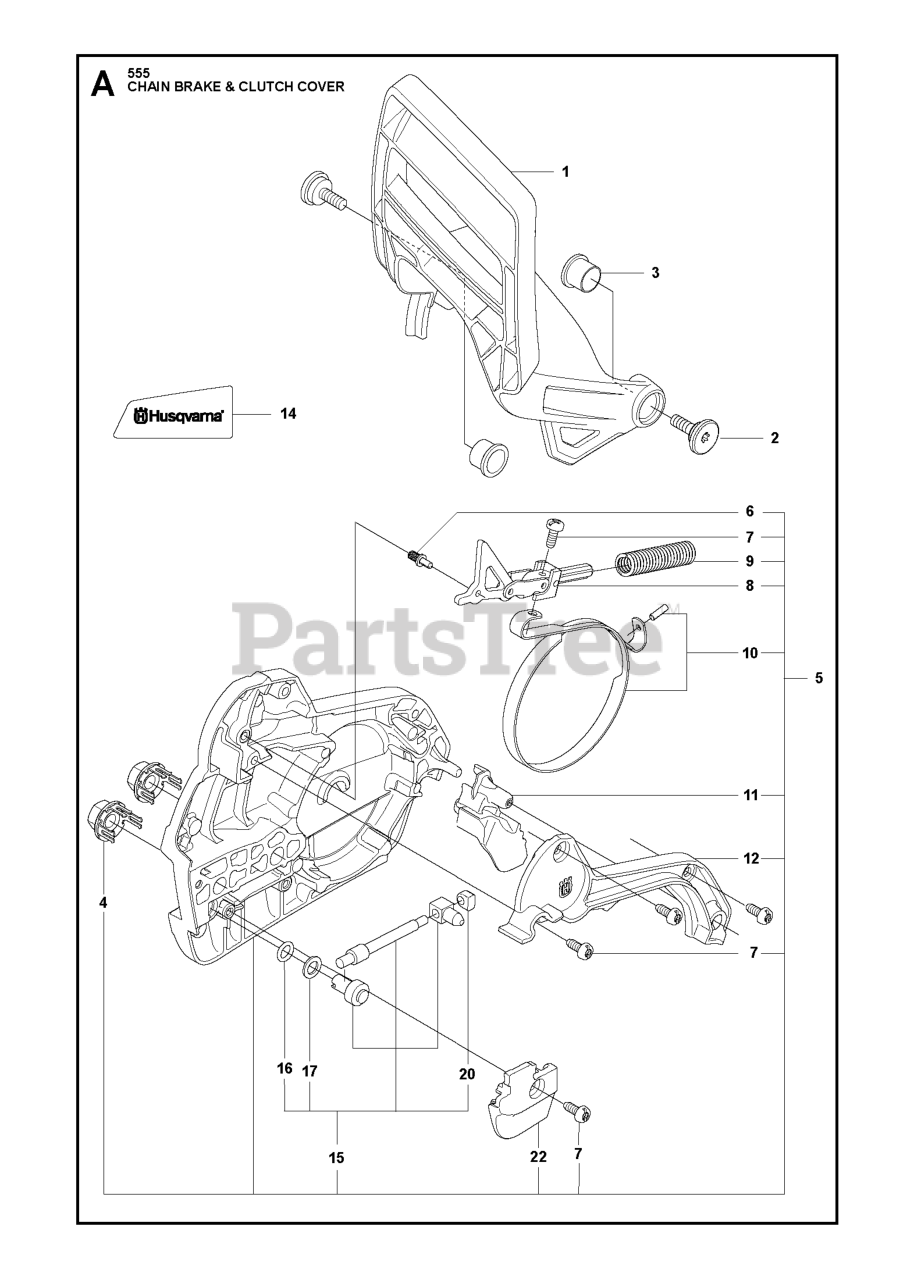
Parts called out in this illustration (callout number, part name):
1	HAND GUARD
4	NUT RETAINER ASSY
5	CLUTCH COVER ASSY 50CC AND 60
8	KNEE JOINT ASSY
9	SPRING
10	BRAKE BAND
14	LABEL
15	CHAIN TENSIONER KIT
22	CHAIN GUIDE
